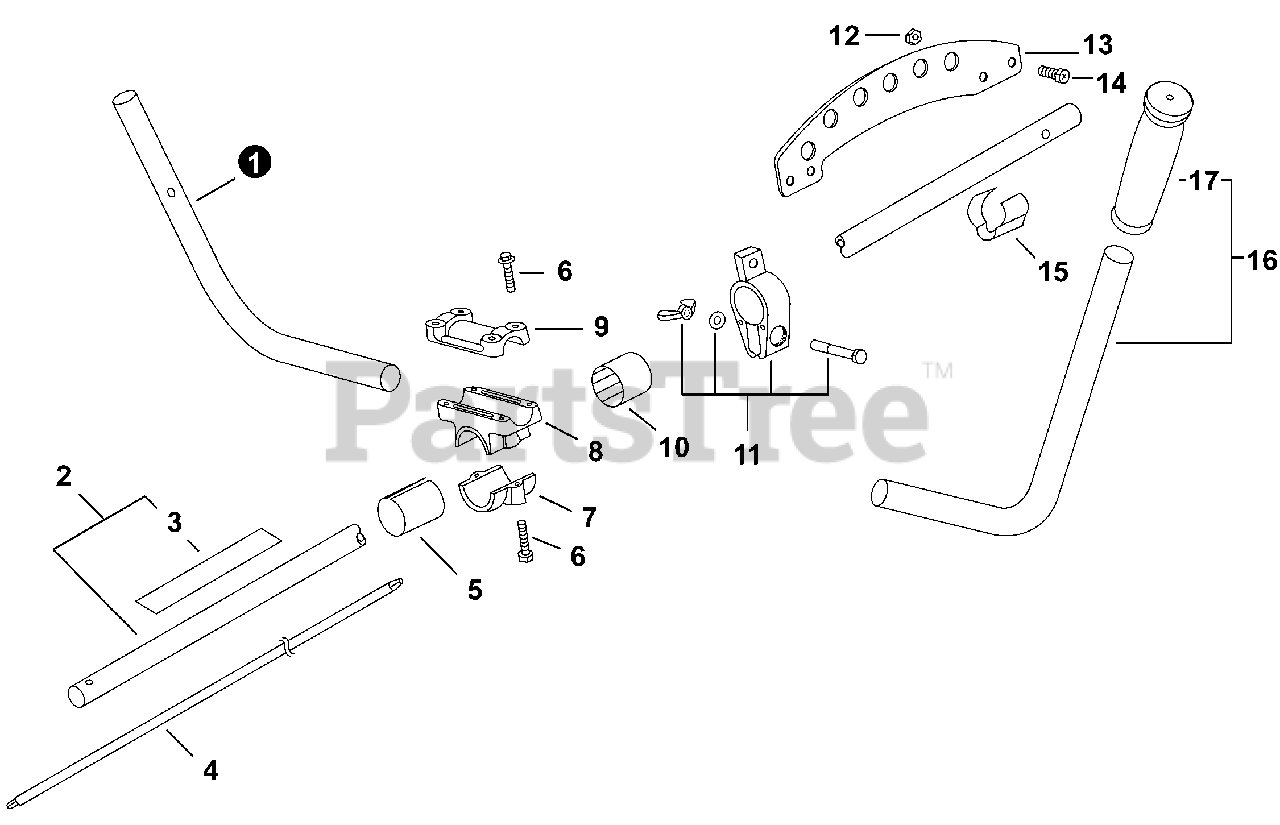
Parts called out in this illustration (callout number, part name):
1	HANDLE, RIGHT
2	PIPE, MAIN
4	DRIVESHAFT
7	BRACKET, MOUNTING
8	BRACKET, LOWER
9	BRACKET, UPPER
11	CLAMP ASSY
14	BOLT 6×16
15	HOLDER, CABLE
16	HANDLE ASSY, LEFT
